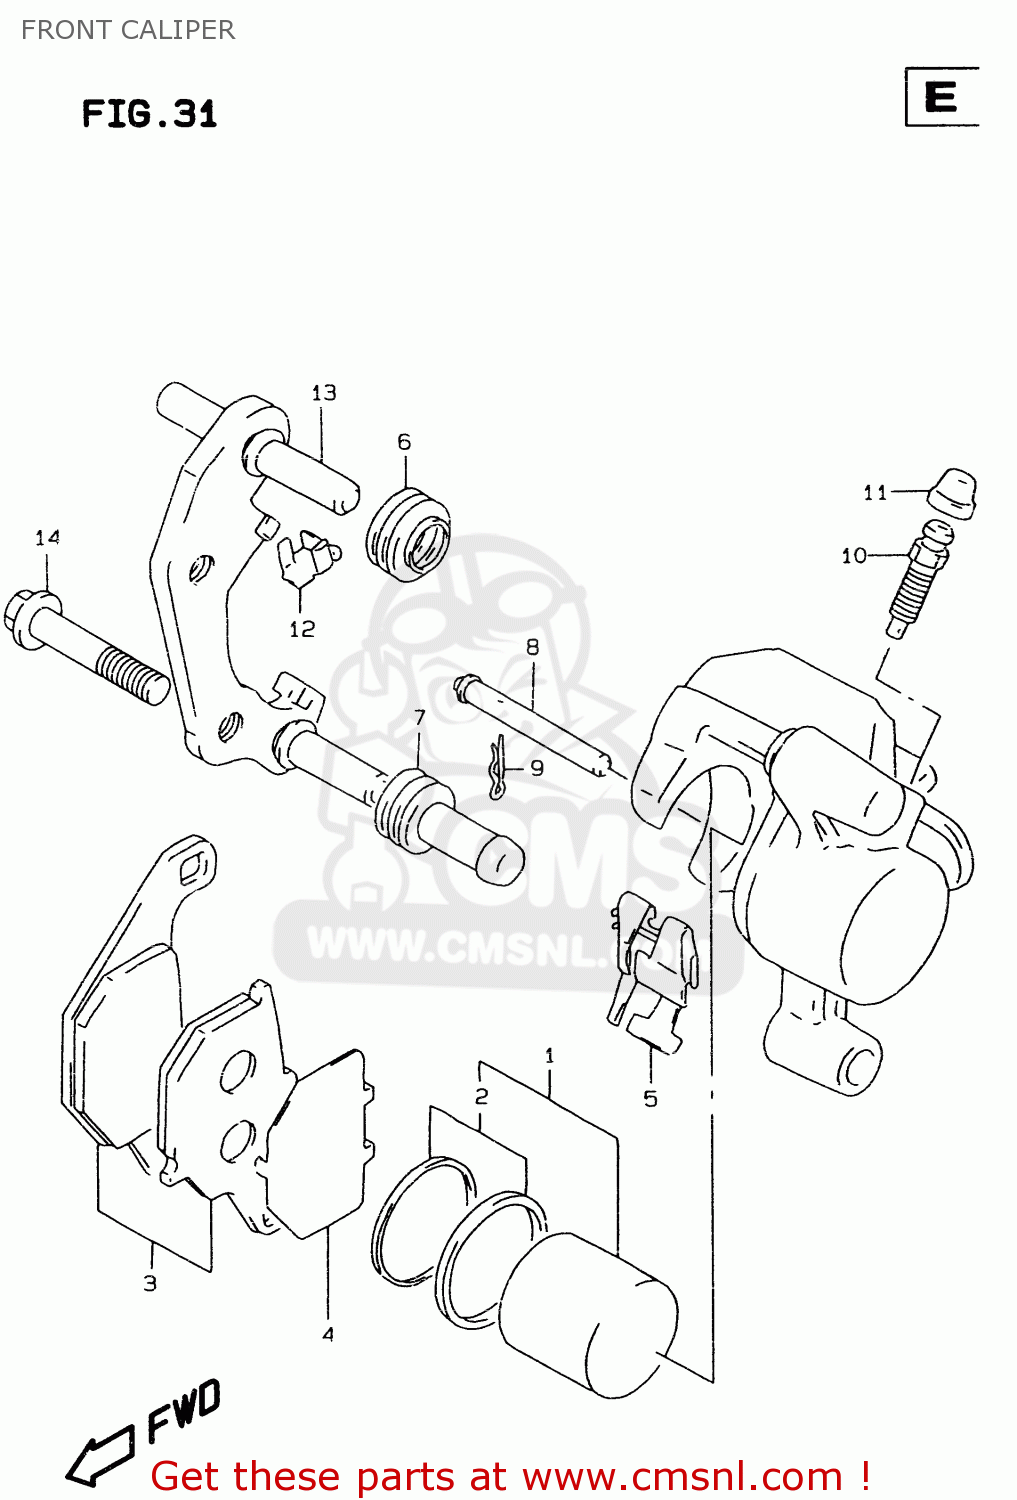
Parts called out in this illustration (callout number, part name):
1	PISTON SET
2	SEAL SET,PISTON
3	PAD SET (NAS)
4	SHIM,PAD
5	SPRING,PAD
6	BOOT,AXLE
7	INSULATOR,AXLE
8	PIN,PAD
9	CLIP,PAD PIN
10	BLEEDER
11	CAP,BLEEDER PLUG
12	GUIDE,PAD
13	CARRIER,CALIPER,L
14	BOLT(8X41)
